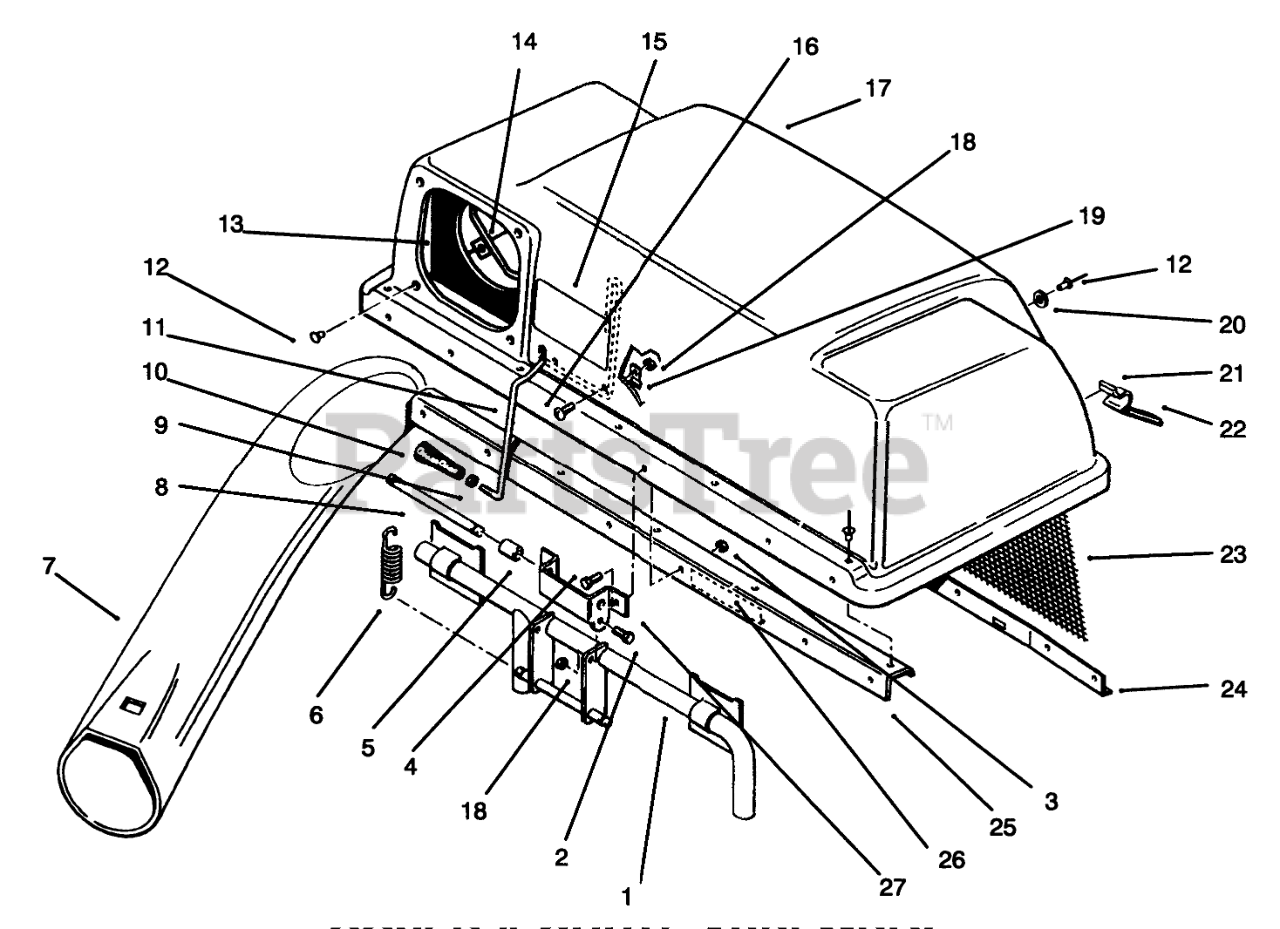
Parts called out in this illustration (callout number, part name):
1	FRAME ASM
2	SCREW-HH
3	NUT-LOCK, NI
4	SCREW-HH
5	SPACER
6	SPRING-EXTENSION
7	CHUTE-BAGGER
8	PIN-SPRING
9	NUT-JAM
10	HANDLE-TAPERED
11	FEELER-FILL, BAG
12	RIVET-BLIND
13	SEAL-CHUTE
14	CLAMP-SEAL
15	DECAL
16	Screw
17	TOP-BAGGER
18	NUT-LOCK, NI
19	CLAMP
20	Washer
21	Latch-Bag
23	SCREEN-BAGGER
24	Screen Support
25	Bagger-Stiffener (Incls. Ref. #26)
26	DECAL-CAUTION
27	HINGE-BAG TOPB
